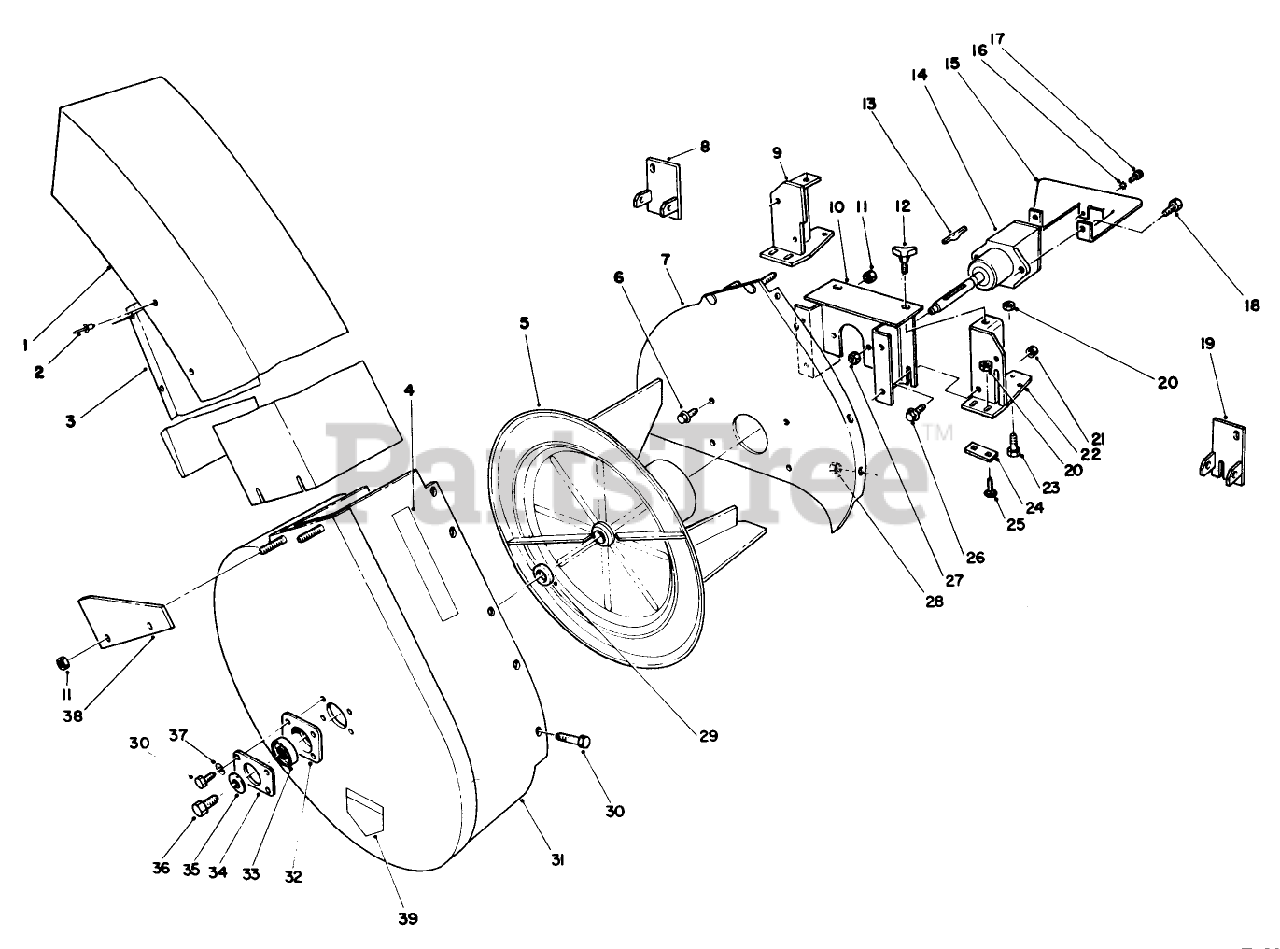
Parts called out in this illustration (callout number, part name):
1	Assembly-Chute (Incl. Ref. #2 & 3)
3	Deflector-Chute
4	DECAL
5	Impeller
6	SCREW-HHF
7	Mounting Plate
8	Bracket-Deflector L.H.
9	LH BRACKET ASM
10	Blower Mount
11	NUT-LOCK, NI
14	Asm-Gear Box
15	Cover-Gear Box
16	WASHER-LOCK, EXT
18	SCREW-HH
19	Bracket-Deflector R.H.
20	NUT-LOCK, CONE
21	NUT-JAM
22	RH BRACKET ASM
23	SCREW-HH
24	Plate-Bracket
25	BOLT-CARR
26	SCREW-HHF
27	NUT-LOCK, NI
28	NUT-LOCK, NI
29	SPACER-BEARING
30	SCREW-HH
31	Housing-Blower (Incl. Ref. #4 & 39)
31	NUT-HEX, SIDE DEFORM
32	CUP-BEARING
33	BEARING-BALL
34	Cover-Plate
35	SPACER
36	SCREW-HH, LOCK
37	WASHER-LOCK
38	Bracket
39	DECAL-DANGER
